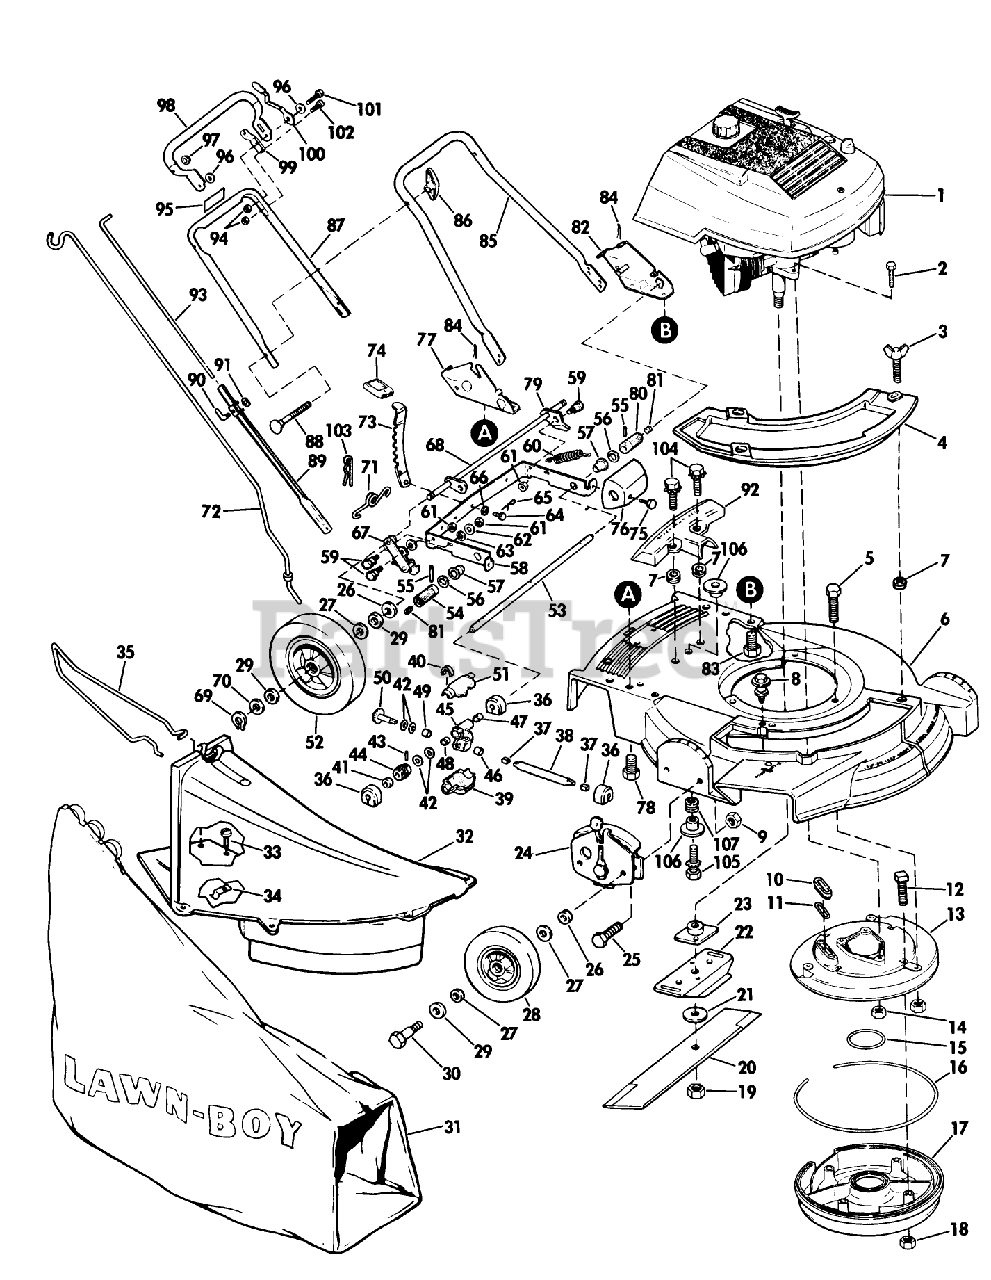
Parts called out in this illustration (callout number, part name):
3	WING SCREW LAWRE
5	SCREW V
11	GASKET S
16	Gasket Muffler (outside)
18	LOCKNUT E
19	NUT-BLADE
23	PLATE AND COLLAR ASM
26	WASHER WROUGHT
30	BOLT WHEEL
42	THRUST WASHER
43	ROLL PIN
49	NEEDLE BEARING
51	GEAR COVER UPPER
59	BOLT RB&W
61	STOP NUT
62	WASHER S
66	WASHER SPRING LAR
69	RET RING
71	SPRING N.A.S
72	ROD GRASSBAG
81	GREASE PLUG
84	HAIR PIN
86	NUT-WING
93	ROD CONTROL
96	WASHER M
100	KNOB & SPRING
101	BOLT RB&W
104	SCREW SEMS TRM HEX HD
106	SPACER ECK PRES
107	GROMMET
